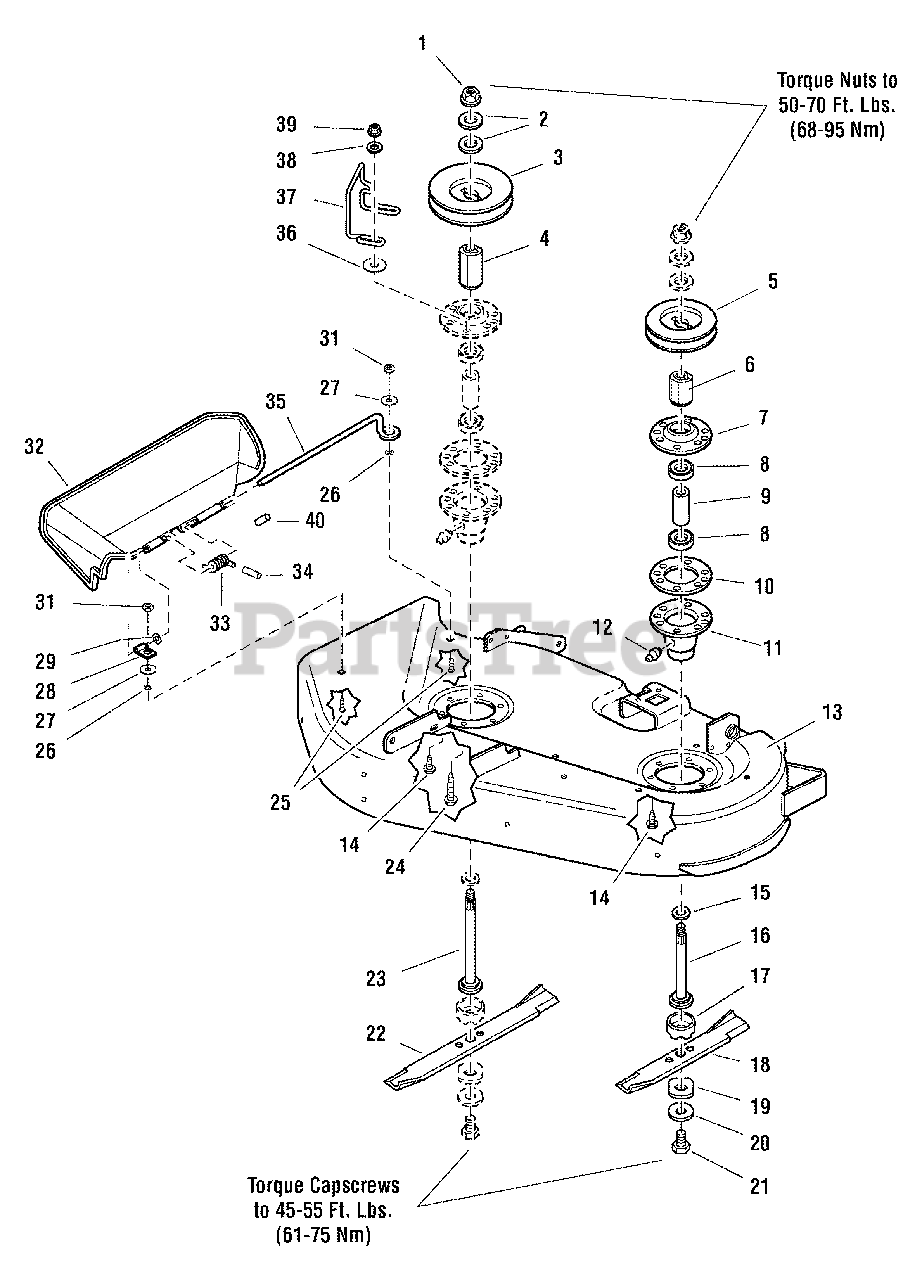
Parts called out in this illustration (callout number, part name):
1	NUT, Hex Flange, 9/16-18
2	WASHER, Belleville
7	COVER, Arbor Housing
10	GASKET, Foam
11	HOUSING ASSEMBLY, Arbor Bottom, w/Lube Fitting
12	FITTING, Lube
13	MOWER HOUSING, 34"
14	CAPSCREW, Hex Washer Head, Taptite, 5/16-18 x 3/4, Black
16	SHAFT, Arbor
17	SHIELD, Grass
18	BLADE, Mower, 14.42
19	WASHER, Hex, Special
20	WASHER, Spring
21	CAPSCREW, Hex Head, 7/16-14 x 1-1/4, Black
22	BLADE, Mower, 19.90
23	SHAFT, Arbor
24	CAPSCREW, Hex Washer Head, Taptite, 5/16-18 x 1-1/2, Black
25	CARRIAGE BOLT, 1/4-20 x 7/8, Black
26	NUT, Push, 1/4, Black
27	WASHER, 1/4, Black
29	WASHER, 5/16, Black
31	NUT, Hex ESNA, 1/4-20, Black
32	DEFLECTOR, Plastic
33	SPRING, Torsion
34	CAP, Spring End
35	ROD, Deflector, Front
36	WASHER, 5/16, Black
38	WASHER, 5/16, Black
39	NUT, Hex Flange, 5/16-18
40	BOOT, Protective
